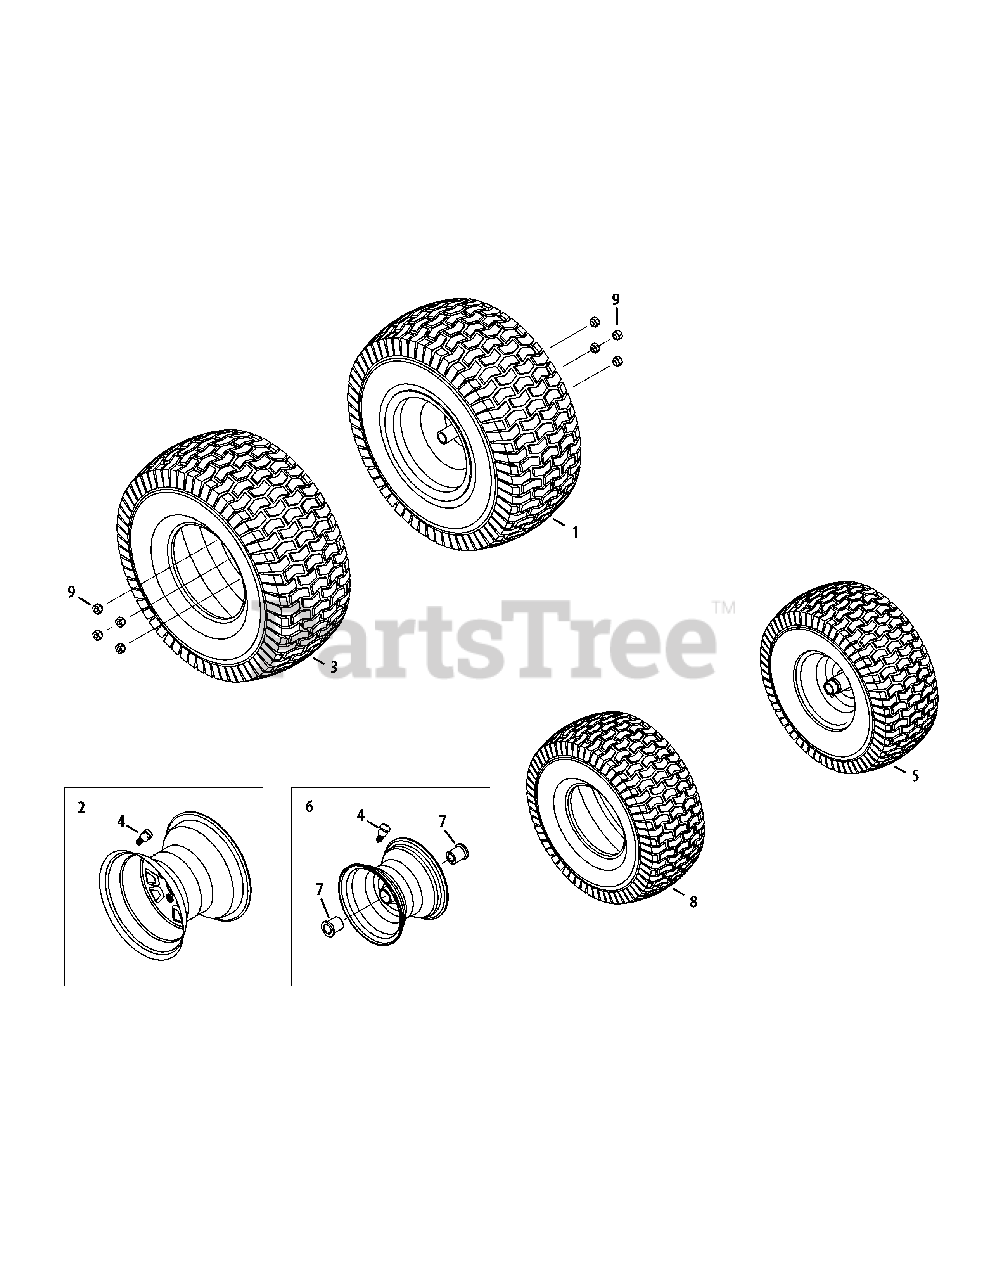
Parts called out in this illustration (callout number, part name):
1	Wheel, Complete, 22 x 9.5 x 12
2	Rim Ass’y, 12.0 x 7.0
3	Tire, 22 x 9.5 x 12 Sq Shoulder
4	Valve, Tubeless Air
5	Wheel, Complete, 16 x 6.5 x 8
6	Rim Ass’y, 8.0 x 5.38
7	Bearing, Flange, .760 ID
8	Tire, 16 x 6.5 x 8 Sq Shoulder
9	Lug Nut 7/16-14
